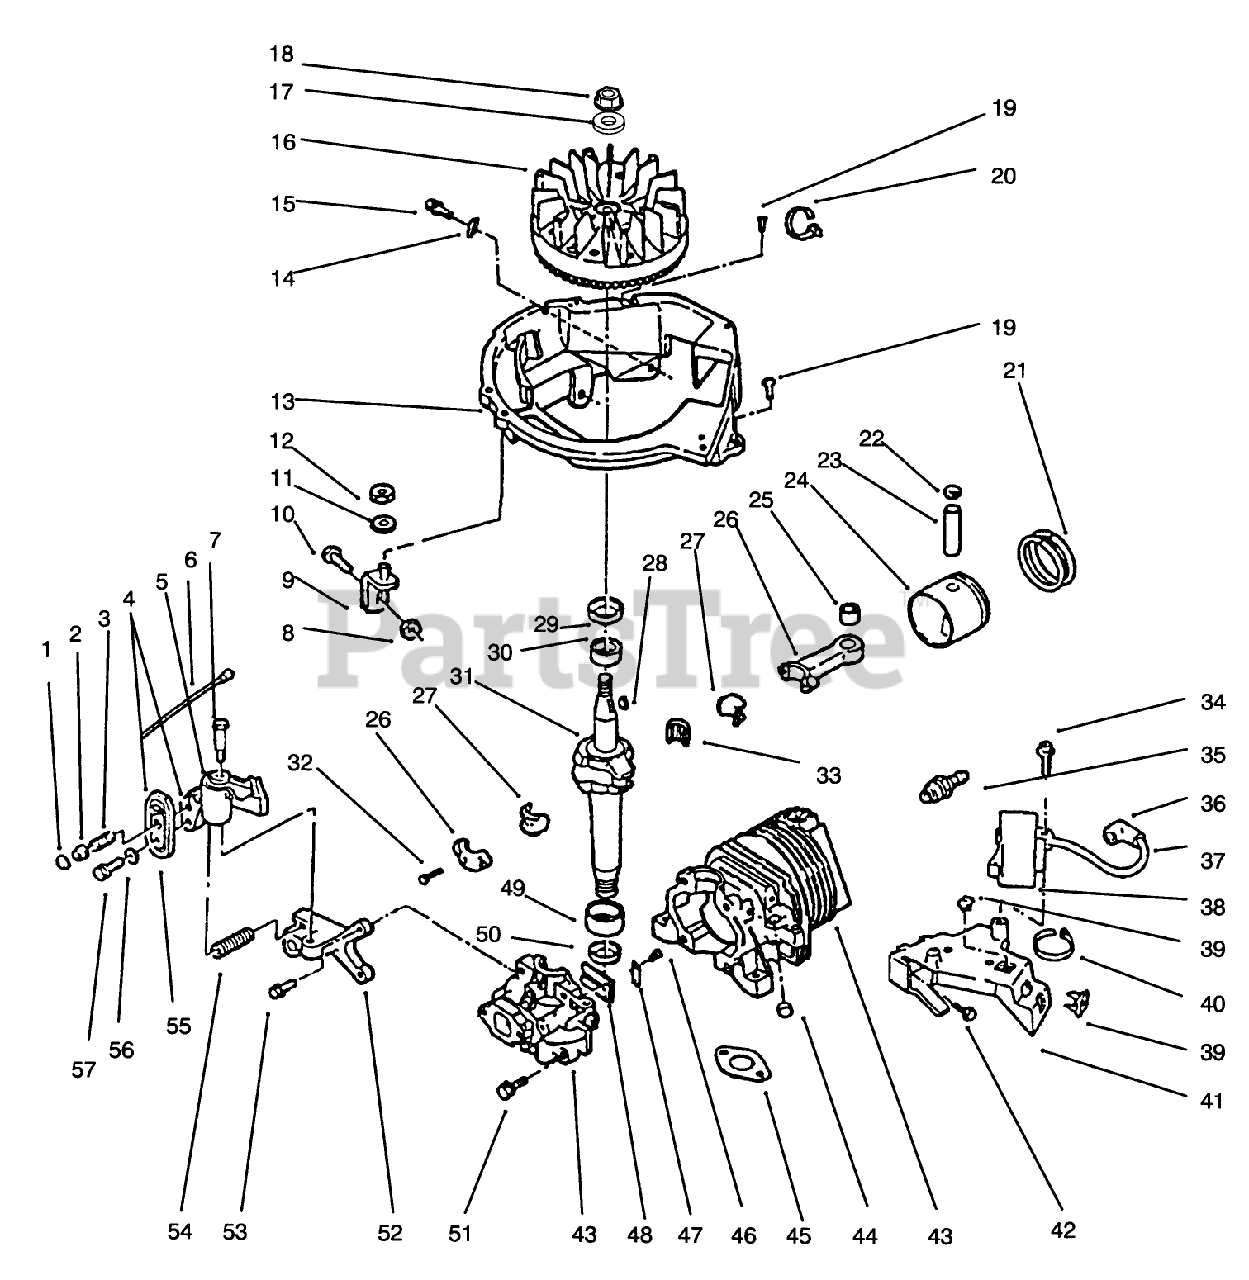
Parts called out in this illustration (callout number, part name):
1	RETAINER S
2	ACTUATOR-LEVER, BRAKE
6	WIRE LEAD AY F
7	SCREW-SHOULDER
8	NUT-LOCK F
9	BRACE AY F
12	LOCKNUT E
13	BASE SHROUD F
15	SCREW-SEMS
16	FLYWHEEL ASSY F
19	SCREW F
22	RING-RETAINING
24	PISTON VF
25	BEARING XEV
26	CONNECTING ROD ASM
27	LINER ASM
29	SEAL-OIL
30	BEARING V
32	SCREW-HSH
33	BEARING-NEEDLE
35	SPARK PLUG
36	COVER & TERM. AY S
37	HT LEAD&COVER XEV
39	NUT-SPEED
40	TIE-CABLE
41	C.D. BRKT F
42	SCREW F
44	PLUG-CORE VF
46	SCREW-HH
47	PLATE-BACKUP, REED
49	BEARING V
50	SEAL-OIL
51	SCREW-H.W.HD. F
52	BRACKET-BRAKE F
54	SPRING-BRAKE
